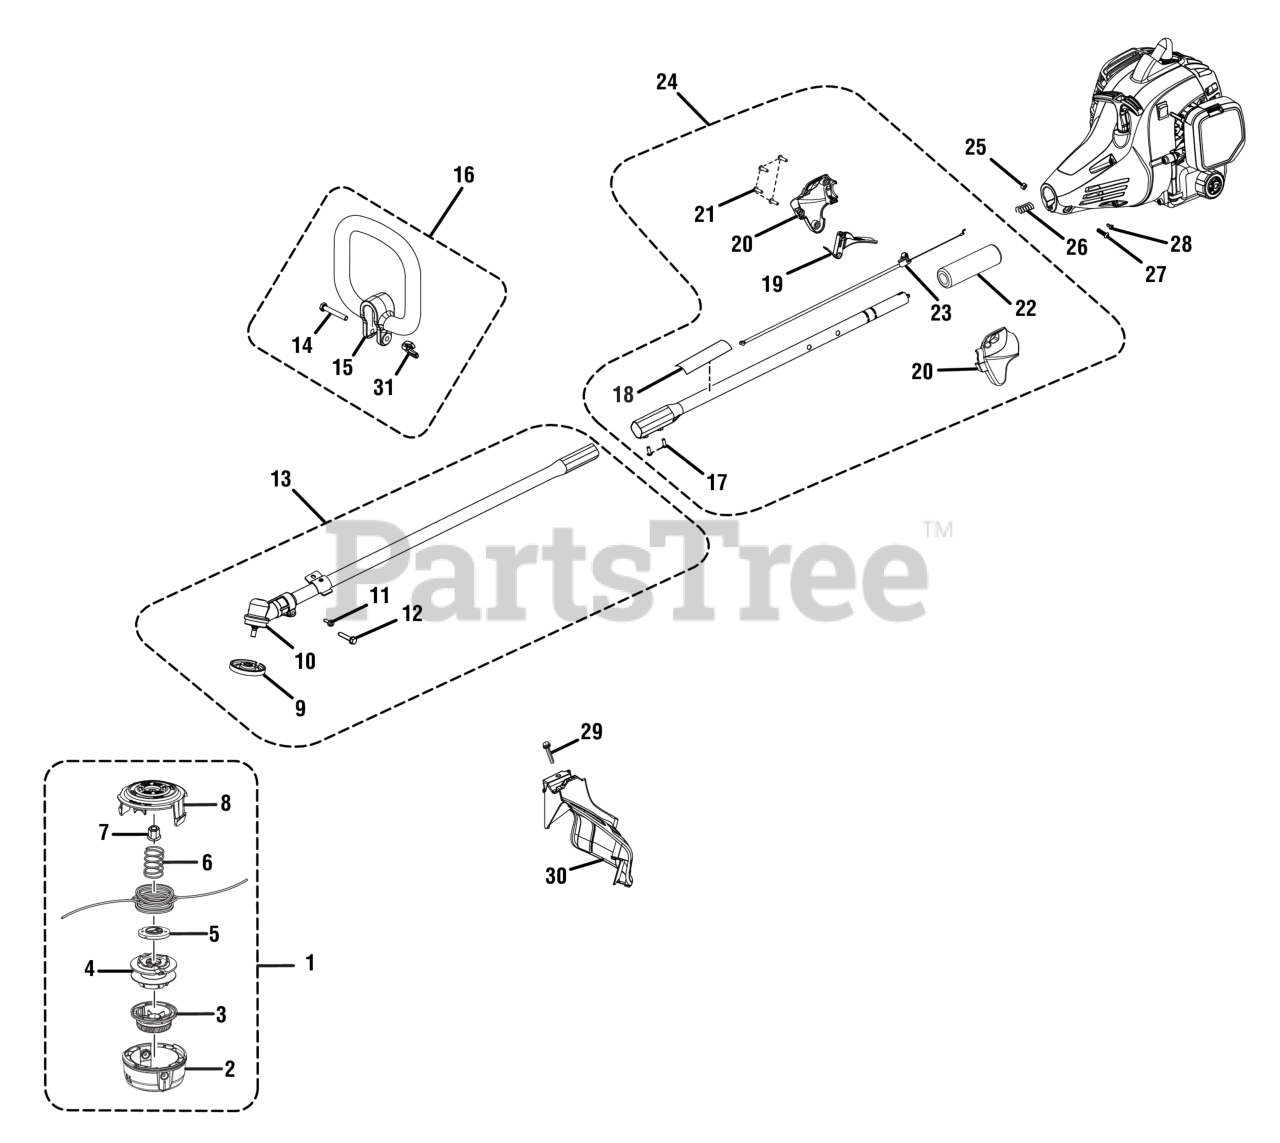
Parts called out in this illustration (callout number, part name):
1	Trimmer Head Assembly
2	Lower Housing
3	Bump Knob (Gray)
4	Spool Assembly
5	String Guide
6	Compression Spring
7	Hex Nut (M8, Left Hand Threads)
8	Upper Housing
9	FLANGED WASHER
10	Gear Head
11	Screw w/Washer (10-24 x 5/8 in., Hex Hd. T.F.)
12	Screw (1/4-20 x 1-1/4 in., Hex Washer Hd. S.T.)
13	Lower Boom Assembly
14	Bolt (1/4-20 x 45 mm, Cap Hex Hd.)
15	Front Handle
16	Front Handle Assembly
17	Set Screw (M5 x 10 mm, Hex Soc. Hd.)
18	Icon Warning Label
19	Throttle Trigger
20	Handle Assembly (Inc. Key Nos. 19 & 21)
21	Screw (M4 x 20 mm, T20 Torx Pan Hd. T.Fl.)
22	Rubber Grip
23	Throttle Cable
24	Boom Assembly (Inc. Key Nos. 17-23)
25	Hex Nut (M6.3 x 1)
26	Compression Spring
27	Screw (M6 x 20 mm, T27 Torx Button Hd.)
28	Screw (M4 x 8 mm, T25 Torx Pan Hd. T.F.)
29	SCREW (#1/4-20 X 1-1/4 in. HEX WASHER HD.)
30	Grass Deflector Assembly
31	Wing Nut (1/4-20, Plastic)
